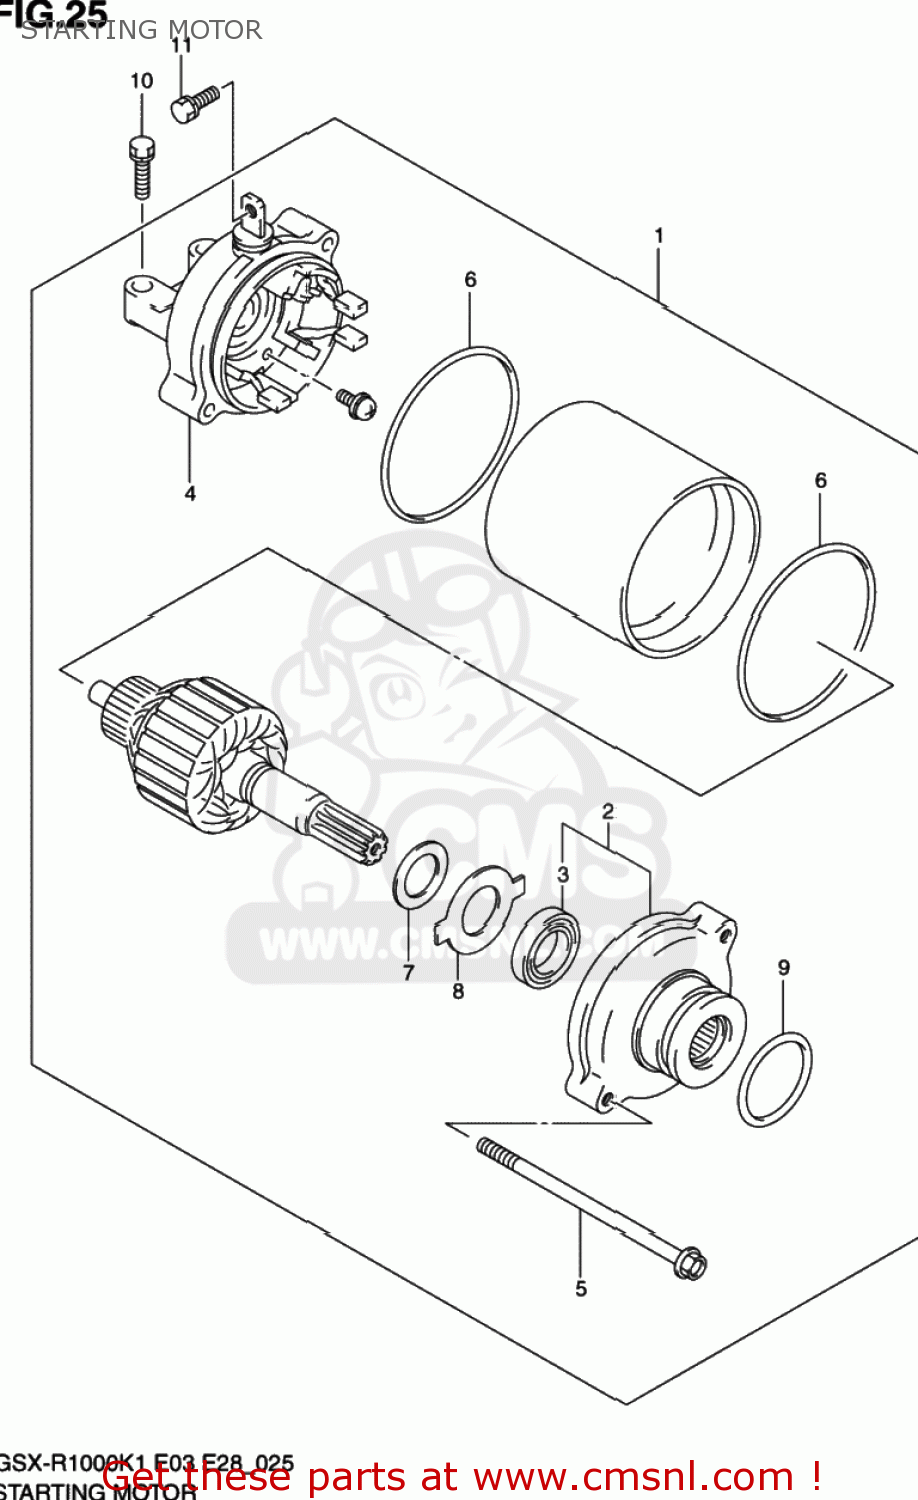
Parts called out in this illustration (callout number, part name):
1	MOTOR ASSY,STARTING
2	HOUSING ASSY
3	SEAL,OIL
4	FRAME ASSY
5	BOLT
6	O RING
7	SHIM
8	PLATE,LOCK
9	O RING(D:3,ID:24.5)
10	BOLT(6X20)
11	SCREW(5X8)
